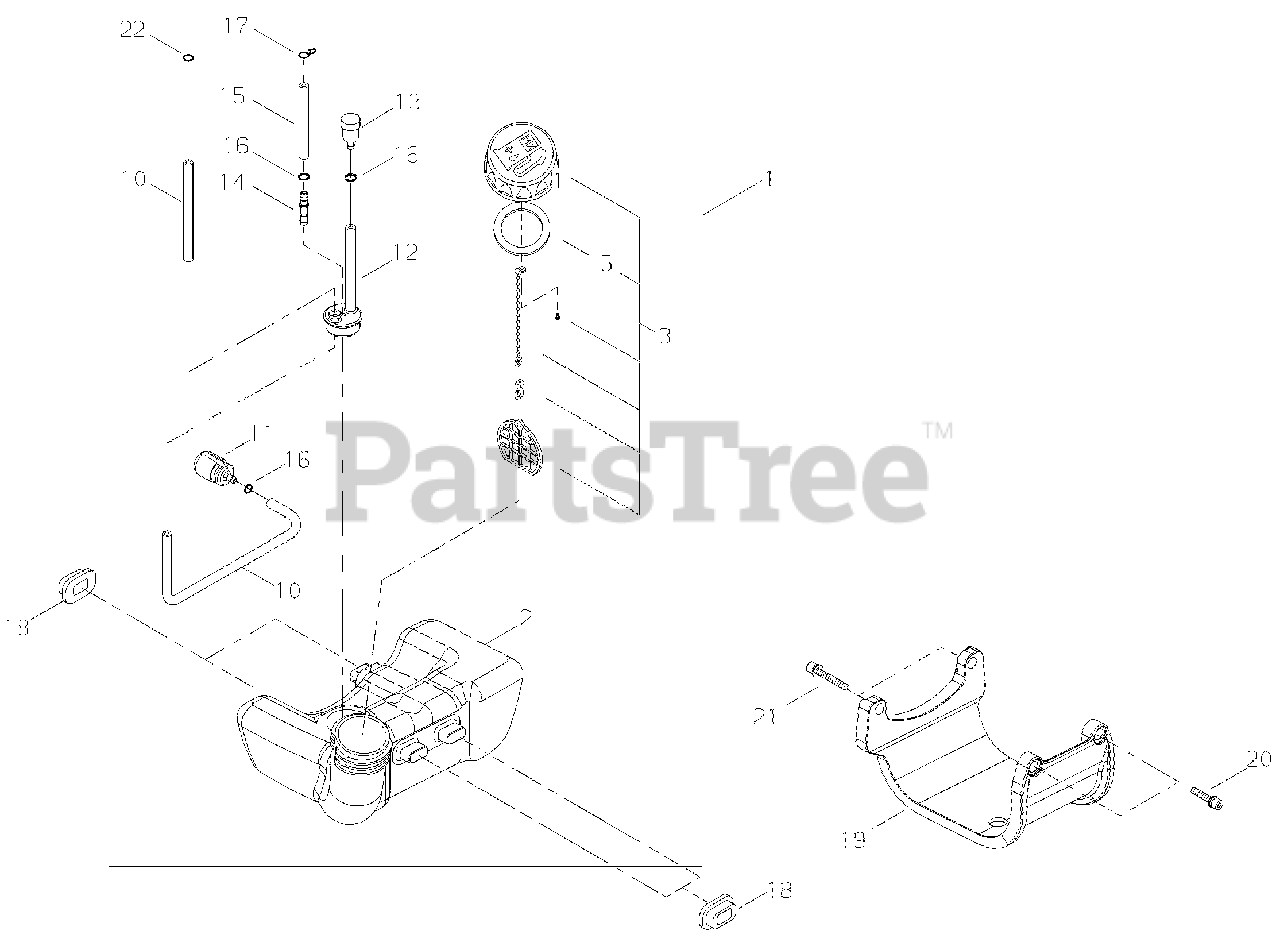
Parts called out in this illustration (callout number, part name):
1	TANK ASSY, FUEL
2	TANK, FUEL
3	CAP ASSY, FUEL
5	GASKET, FUEL CAP
10	PIPE, FUEL 3.3×6×215
11	FILTER, FUEL 125-528
12	GROMMET, FUEL W/VENT PIPE
13	VENT ASSY
14	CONNECTOR, PIPE
15	PIPE, FUEL RETURN
16	CLIP Ø6
17	CLIP, SPRING Ø5.2
18	CUSHION, FUEL TANK
19	GUARD, FUEL TANK
20	BOLT M5×18
21	BOLT M5×40
22	CLIP Ø6
